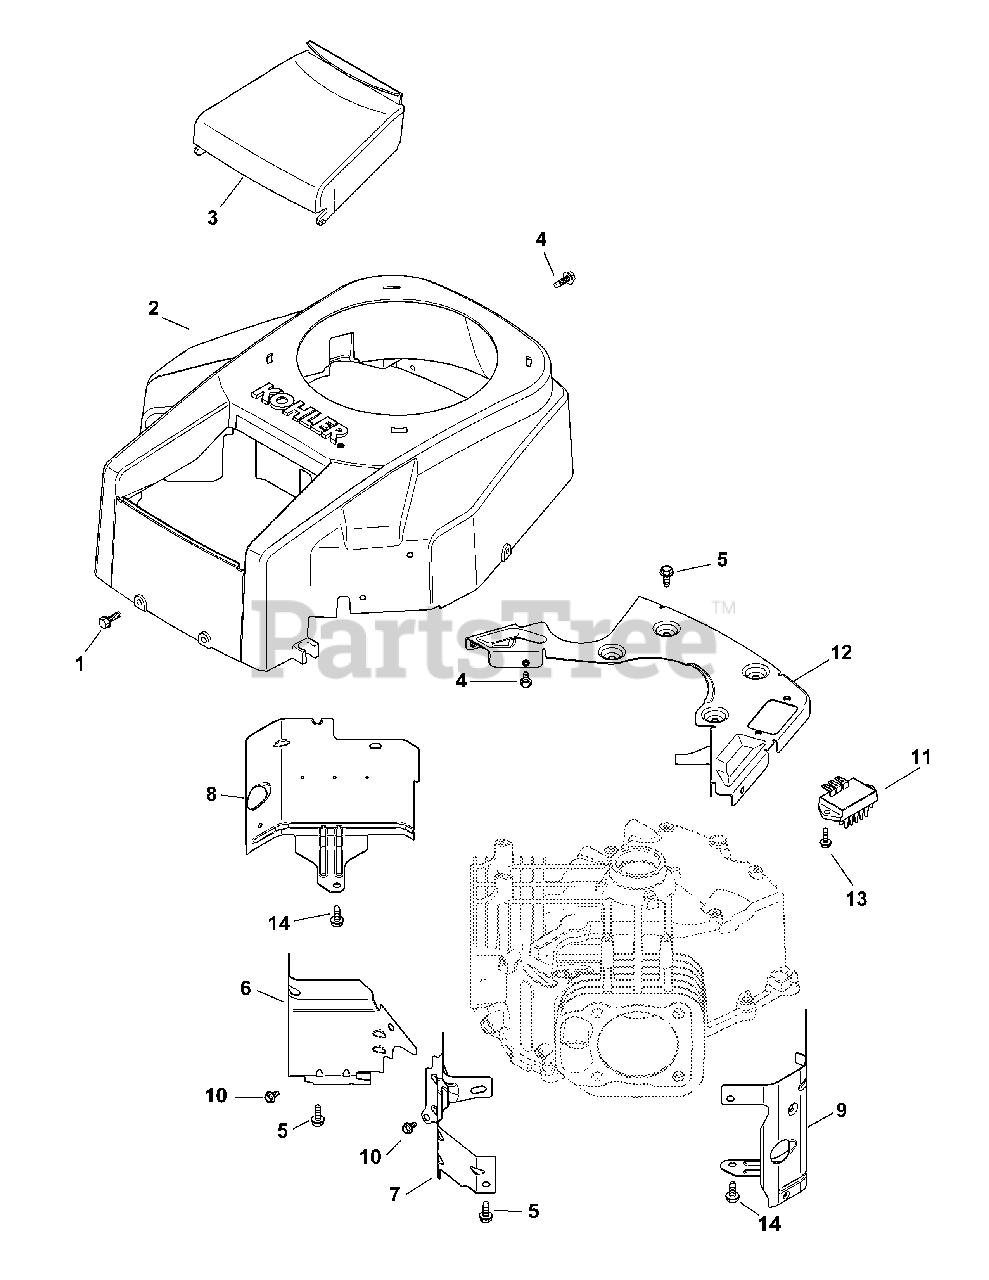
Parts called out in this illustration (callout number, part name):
1	Screw, M6 x 1.7 x 18
2	Blower Housing Kit
3	Air Cleaner Cover
4	Flange Screw, M5 x .8 x 16
5	Flange Screw, M6 x 1.0 x 16
6	Valley Baffle, #1 Cylinder
7	Valley Baffle, #2 Cylinder
8	Cylinder Barrel Baffle, #1 Side
9	Cylinder Barrel Baffle, #2 Side
10	Flange Screw, M5 x .8 x 10
11	Regulator/Rectifier
12	Backing Plate Kit
13	Screw, M5 x .8 x 20
14	Flange Screw, M6 x 1.0 x 10
